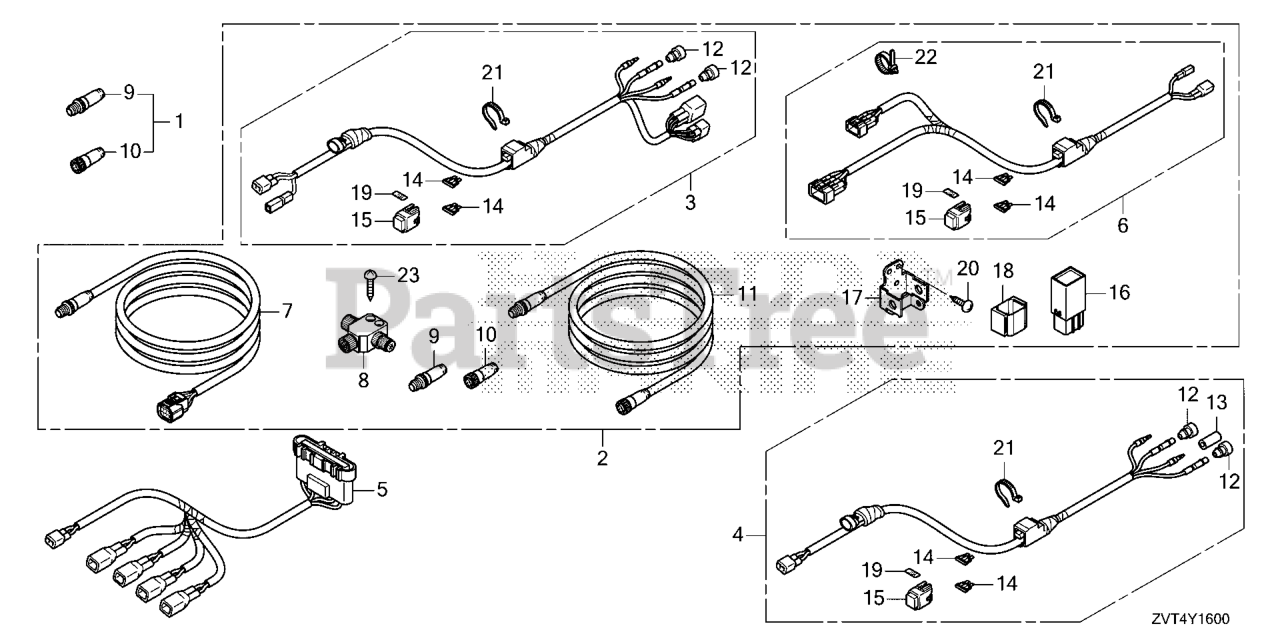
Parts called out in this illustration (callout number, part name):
1	CONNECTOR KIT, TERMINATOR
9	TERMINATOR (M)
10	TERMINATOR (F)
